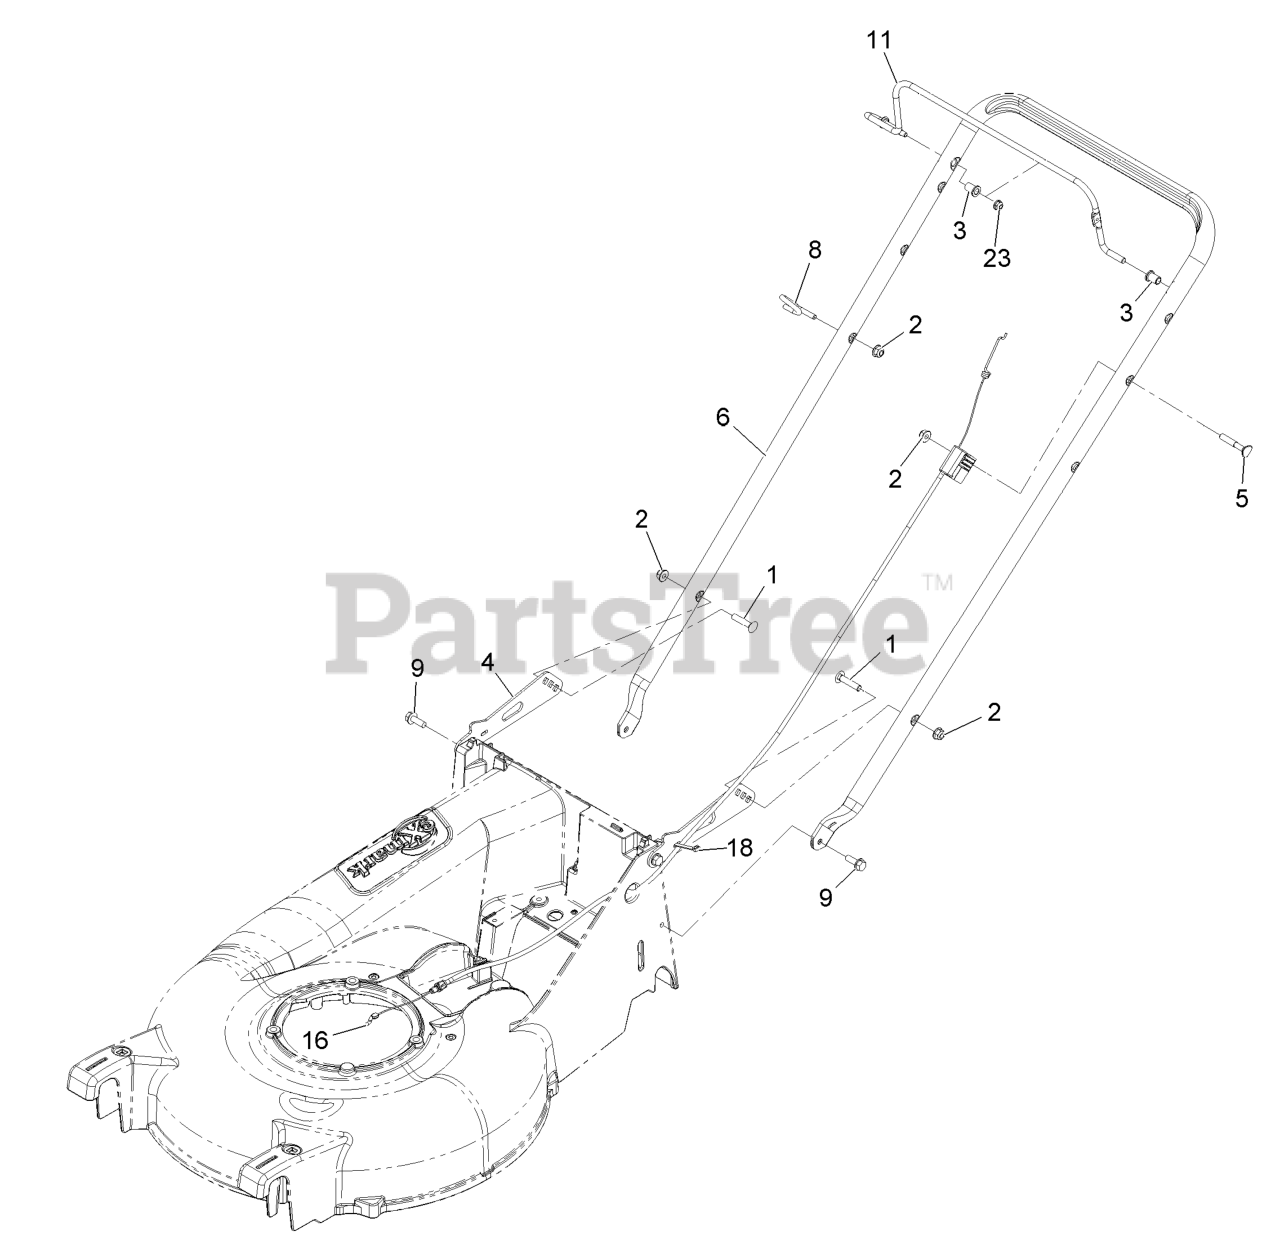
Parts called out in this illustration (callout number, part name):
1	BOLT-CARR
2	NUT-HF, NI
3	BUSHING-HANDLEBAR
4	BRACKET,HANDLEBAR
6	HANDLEBAR-P21
8	GUIDE,ROPE
9	SCREW-TAPTITE
11	BAIL,OPC/BBC
16	CABLE-ZONE KAWASAKI
18	TIE-CABLE
